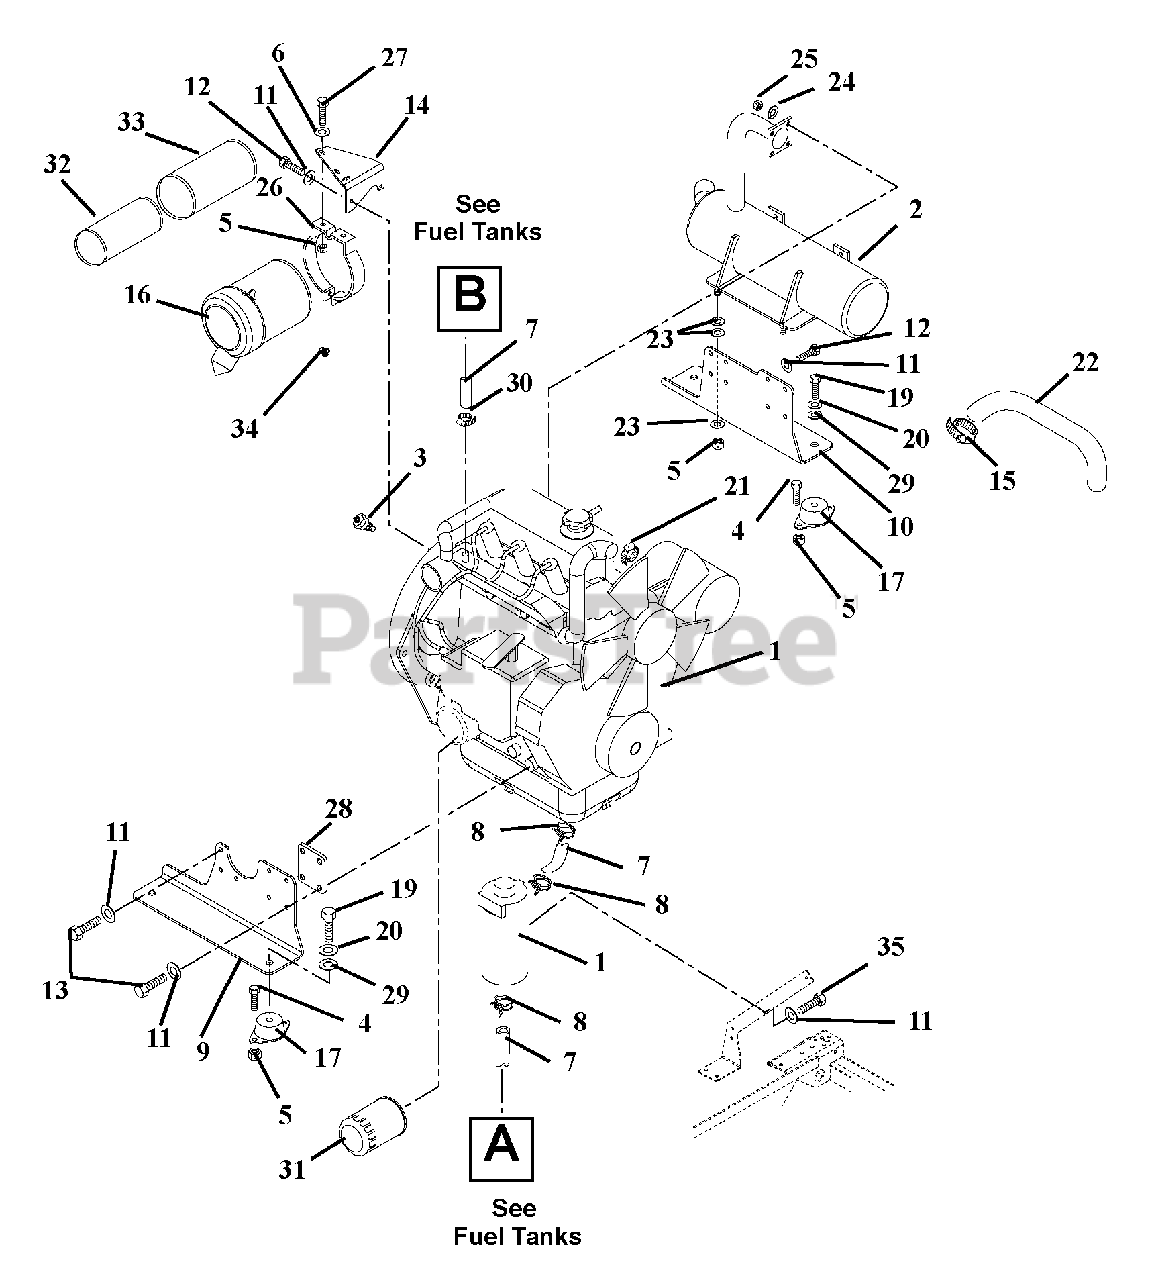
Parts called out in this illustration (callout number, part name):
1	Engine, 27HP Daihatsu Diesel
1	Engine, 31HP Dahatsu Diesel
2	Muffler
3	Sender, Temperature
4	Bolt, Hex .31-18 x .75 Grade 5
5	Nut, Locking Top Flange .31-18
6	Washer, Locking .25 x .062 Regular
7	Gas Line, Bulk .31" ID
8	Hose, Clamp
9	Mount, Engine Right Hand
10	Mount, Engine Left Hand
11	Washer, Lock .31 x .078 Regular
12	Bolt, Hex M8-1.25 x 20
13	Bolt, Hex M8 x 1.25 x 25 Grade 8
14	Bracket, Air Cleaner
15	Clamp, 2.50" Dia. Hose
16	Assembly, Air Cleaner
17	Mount, Engine
18	Bolt, Hex .31-18 x 1.00 Grade 5
19	Bolt, Hex .50-20 x 1.00 Grade 5
20	Washer, Locking .50 x .125 Regular
21	Clamp, Hose 1.50 x .81 x 1.42
22	Hose, Air Cleaner
23	Washer, Flat Steel .38 x .875 x .083
24	Washer, Locking .31 x .078 Regular
25	Nut, Hex M8-1.25
26	Bracket, Air Cleaner Mount
27	Washer, Flat Steel .38 x .875 x .083
28	Spacer, Engine Mounting
29	Washer, Flat Steel .531 x 1.06 x .095
30	Hose Clamp
31	Oil Filter
32	Element, Inner Safety
33	Element, Outer Primary
34	Plug, Pipe .125-27
35	Bolt, Hex M6-1 x 16
